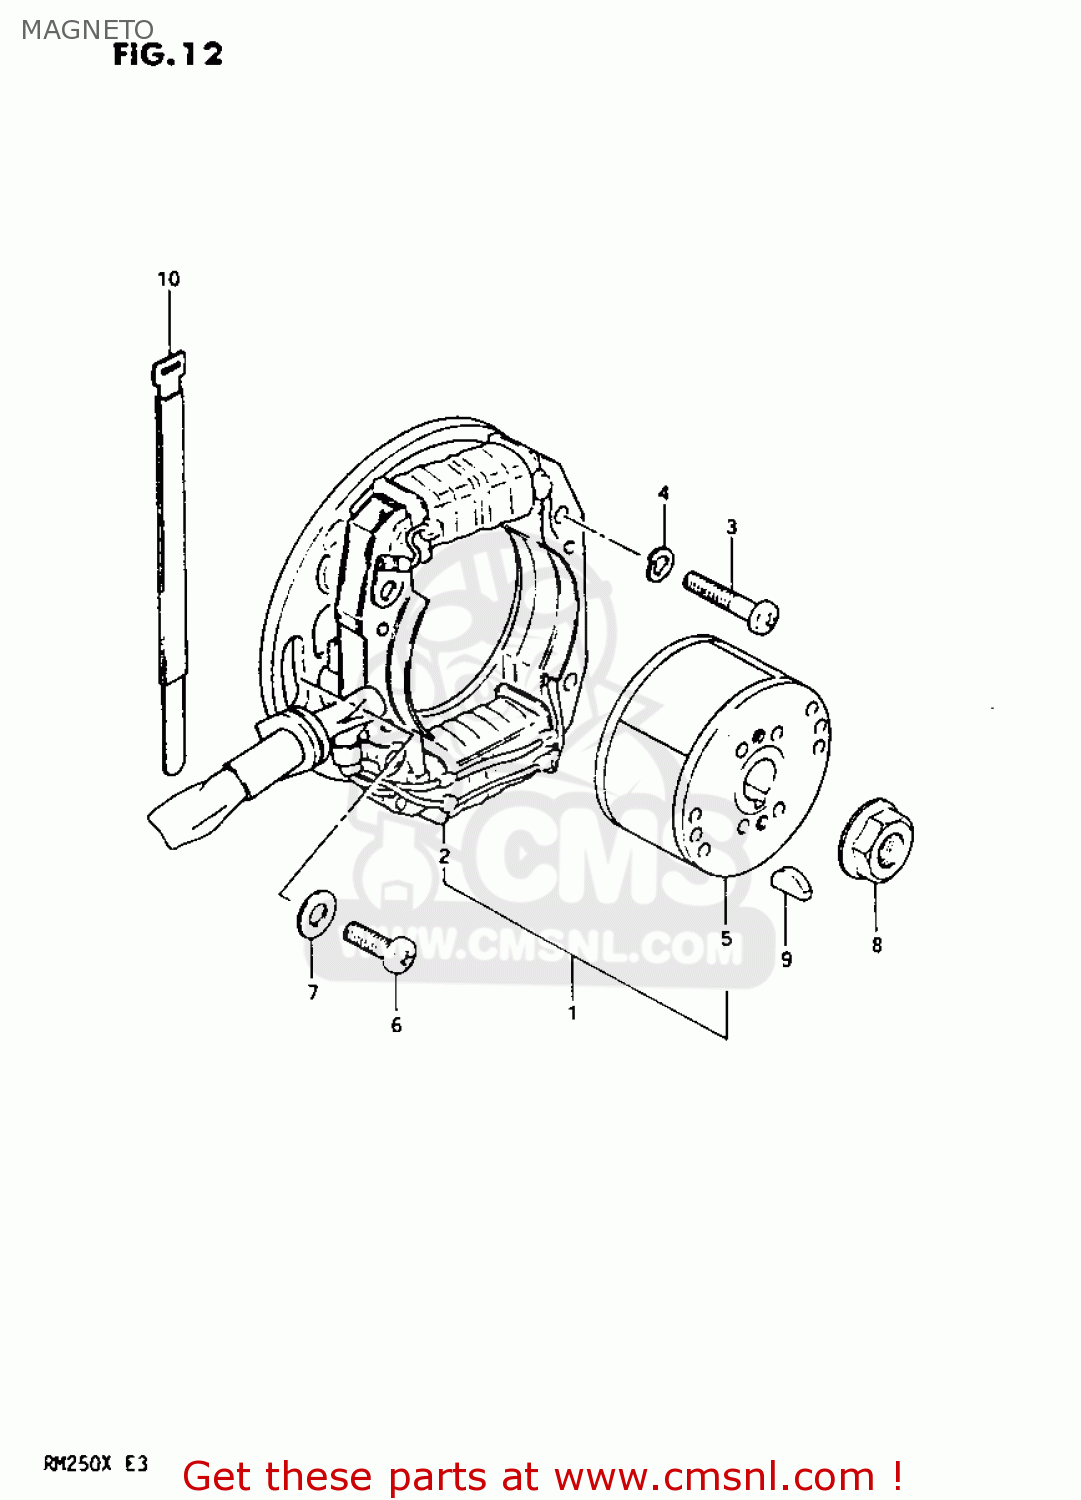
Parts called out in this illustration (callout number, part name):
1	MAGNETO ASSEMBLY
2	STATOR ASSEMBLY
3	SCREW
4	LOCK WASHER
5	ROTOR ASSEMBLY
6	SCREW
7	WASHER
8	NUT
9	KEY 4MM
10	CLAMP
